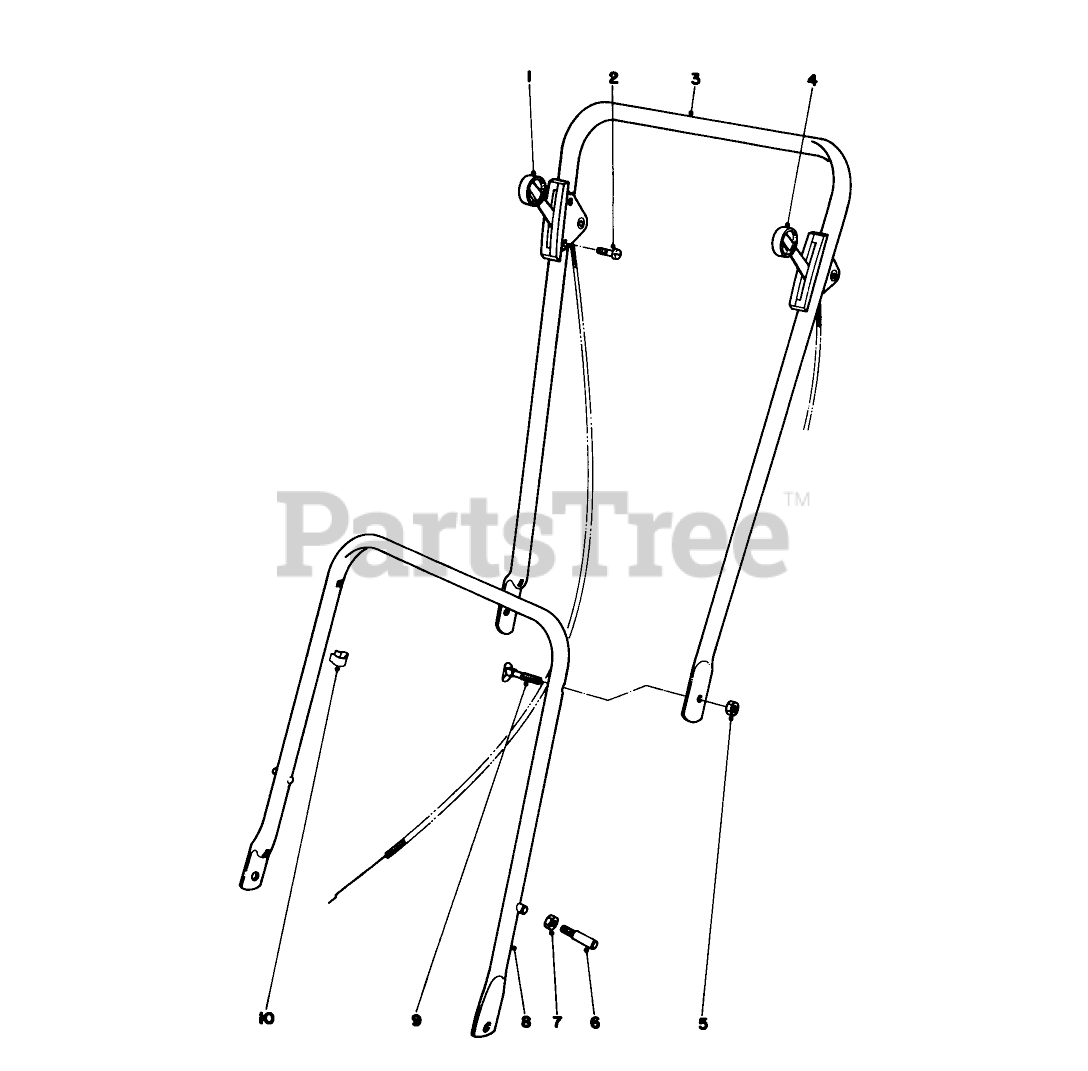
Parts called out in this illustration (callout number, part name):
1	Throttle Control
2	10-24 X 1 PAN HD SCR
3	Handle-Upper
4	Traction Control
5	Nut
6	HANDLE PIN
7	Nut
8	LWR HANDLE STAKED ASM
9	1-1/4 LG HANDLE SCREW
10	CONTROL WIRE CLIP
